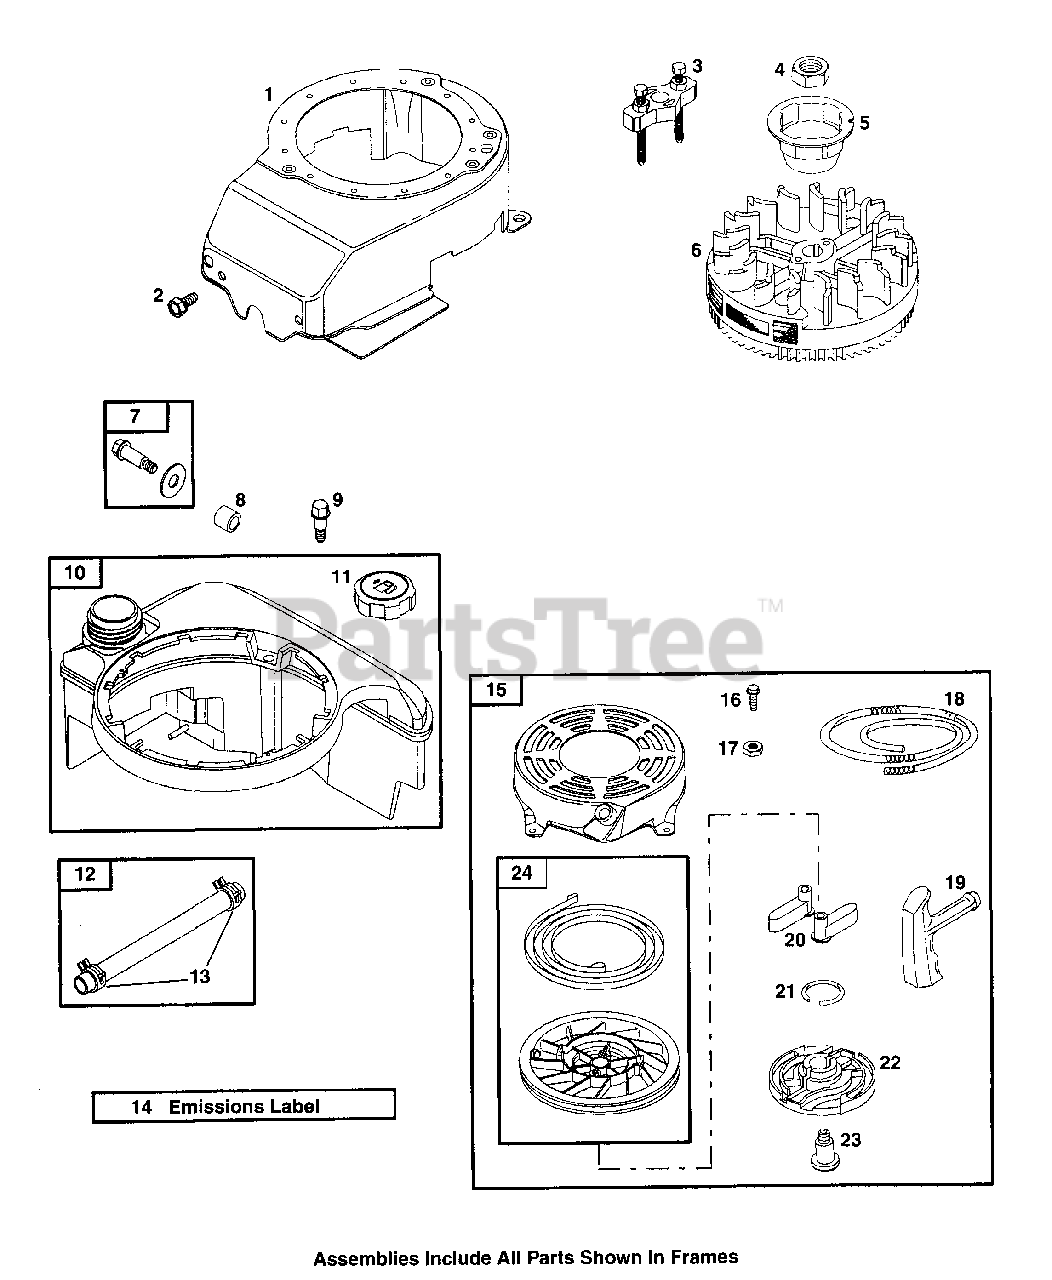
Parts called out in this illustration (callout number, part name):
1	Blower Housing
2	Screw (Blower Housing)
3	Flywheel Puller
4	Nut (Flywheel)
5	Flywheel Cup
6	Flywheel
7	Screw/Washer Kit
8	Fuel Tank Spacer
9	Screw (Fuel Tank)
10	Fuel Tank
11	Fuel Tank Cap
12	Fuel Line
13	Hose Clamp
14	Emissions Label
15	Rewind Starter
16	Screw (Rewind Starter)
17	Nut (Rewind Starter Housing)
18	Starter Rope
19	Starter Rope Grip
20	Ratchet Pawl
21	Friction Spring
22	Pawl Friction Plate
23	Screw (Pawl Friction Plate)
24	Pulley/Spring Assembly
